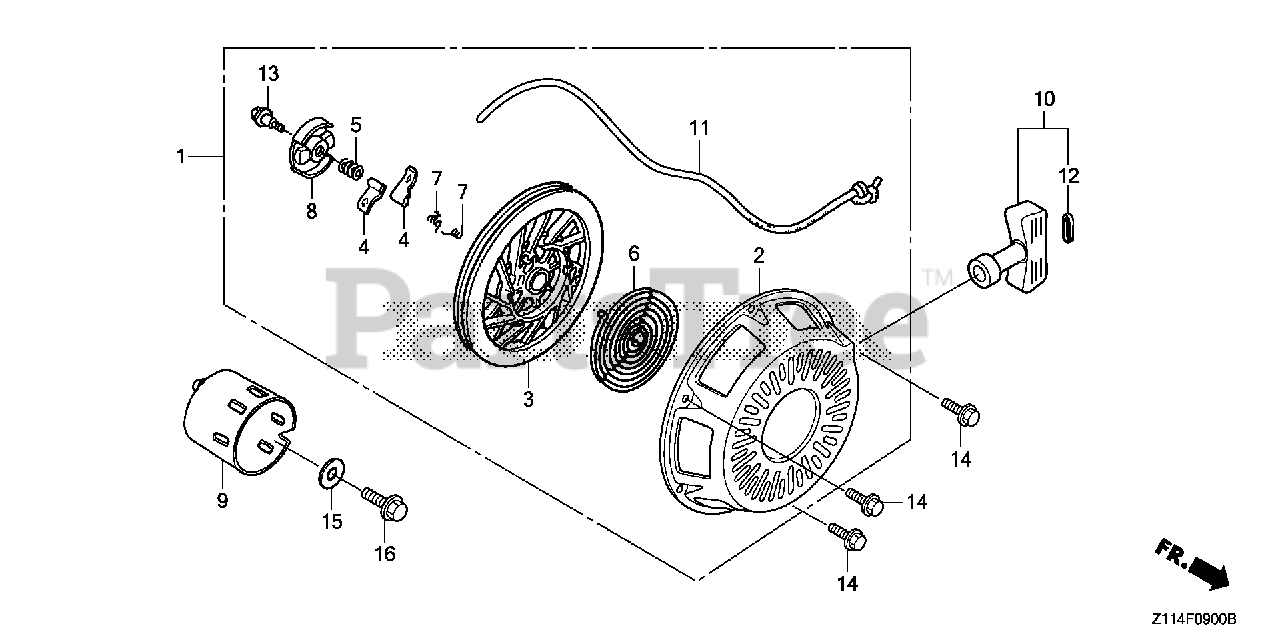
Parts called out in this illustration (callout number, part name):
1	STARTER ASSY., RECOIL
2	CASE, RECOIL STARTER
3	PULLEY, RECOIL STARTER
4	RATCHET, STARTER
5	SPRING, FRICTION
6	SPRING, STARTER RETURN
7	SPRING, RATCHET
8	RETAINER, SPRING
9	PULLEY, STARTER
10	GRIP ASSY., STARTER
11	ROPE, RECOIL STARTER
12	GRIP, REINFORCEMENT
13	SCREW, CENTER
14	BOLT, FLANGE (6X12) (CT200)
15	WASHER (10MM)
16	BOLT, FLANGE (10X25)
